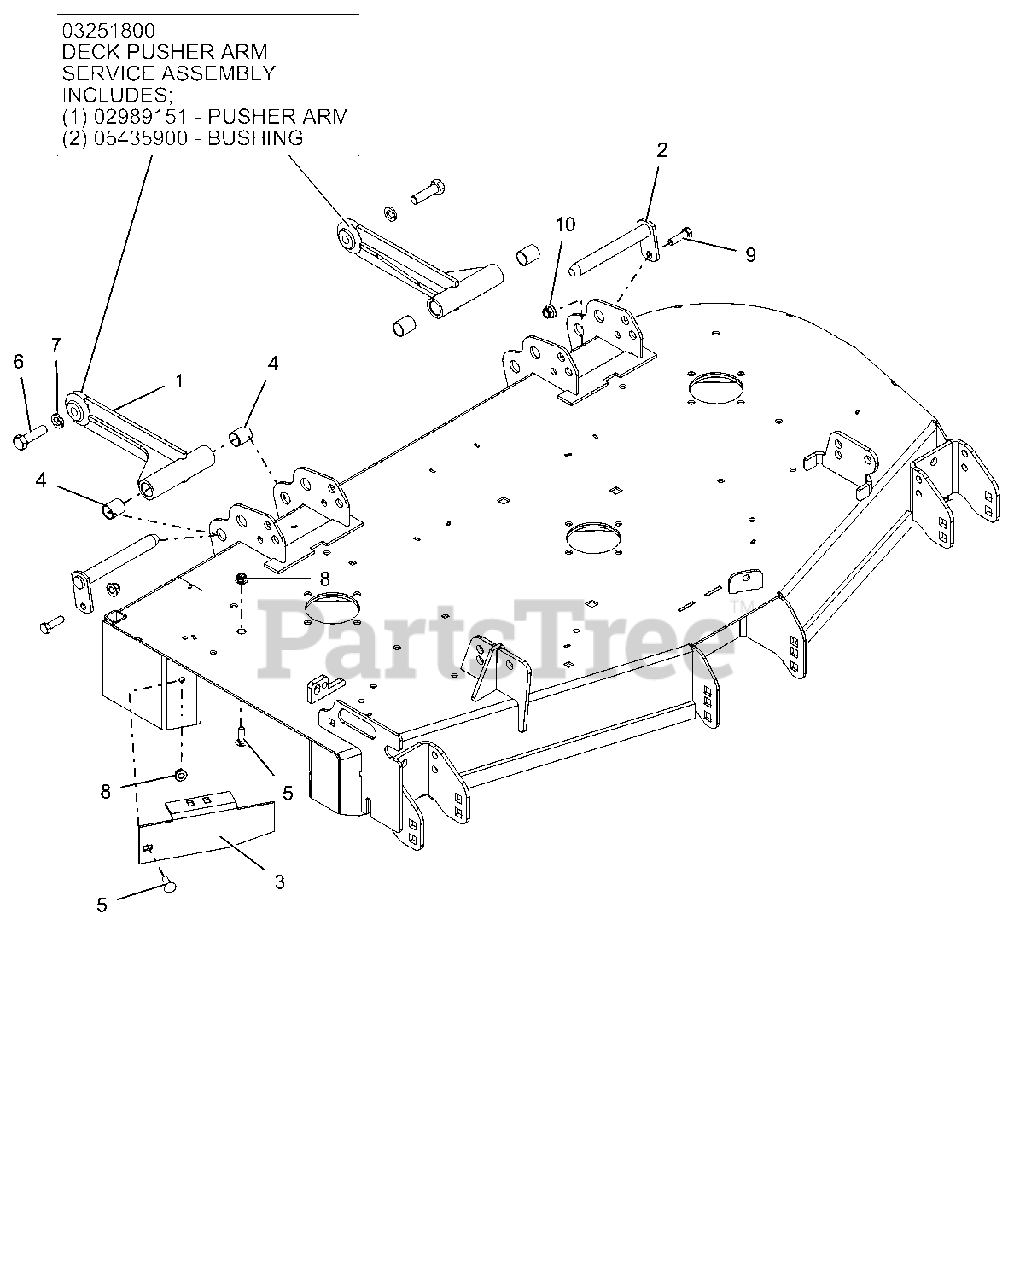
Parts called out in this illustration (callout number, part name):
1	BRG, .750 X .875 X 1.000
1	DECK PUSHER ARM WMT - BLACK
1	DECK PUSHER ARM ASSEMBLY
2	WELDMENT, MOWER MTG. PIN
3	BAFFLE, DISCHARGE 44/48
4	BRG, .750 X .875 X 1.000
5	@BLT-RDHDSQNK .31-18X1.00 G5YZ
6	BLT-HEX .50-13X1.75 GR5EP80 YZ
7	@WSHR-LK .50X.125 REG YWZC
8	@NUT-LK-NYL-FLG .31-18 YWZC
9	@BLT-HEX .38-16X1.25 GR5 YWZC
10	@NUT-LK-NYL-FLG .38-16 YWZC
